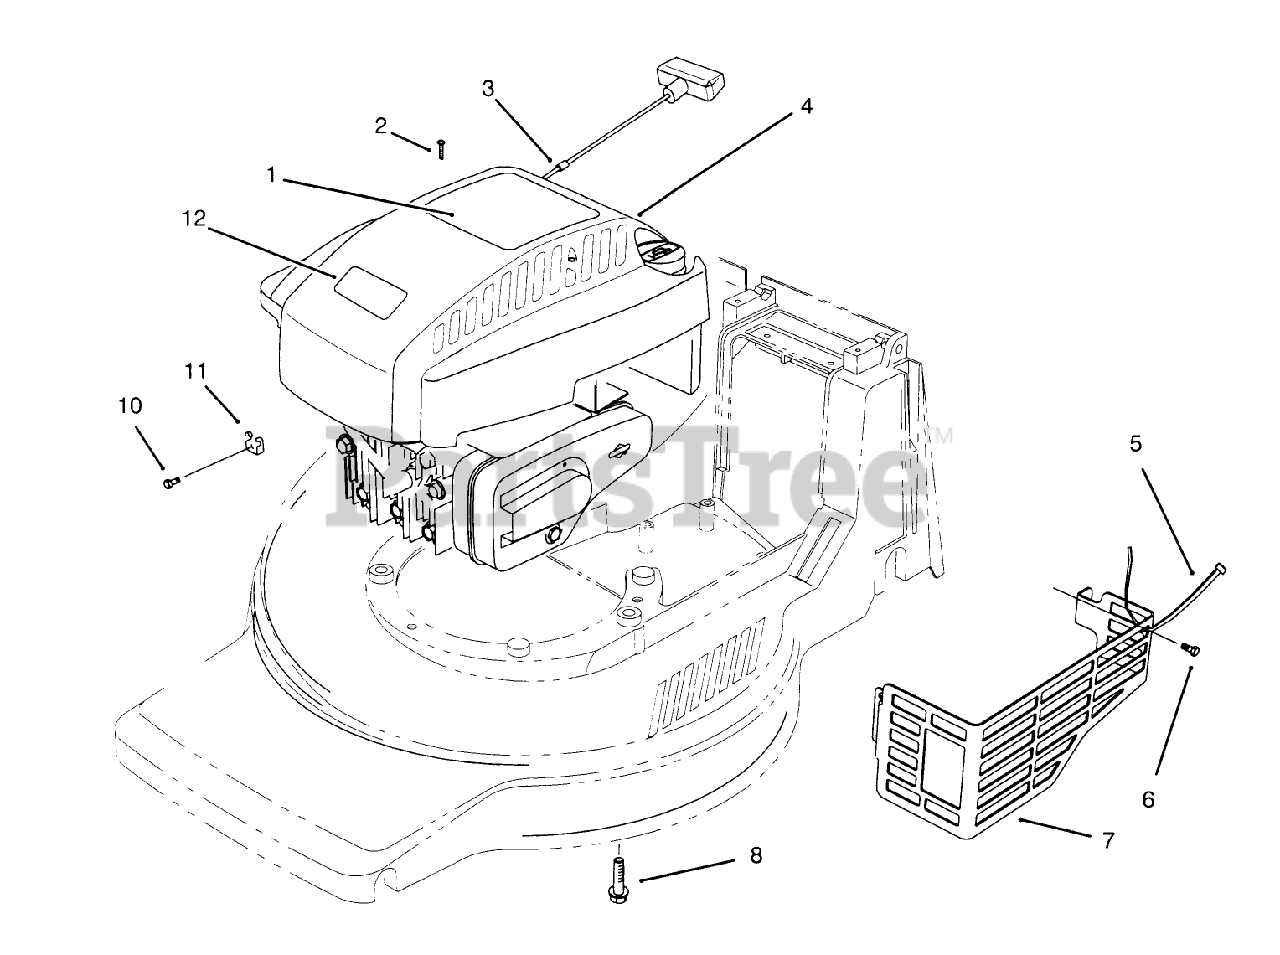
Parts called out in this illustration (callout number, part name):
1	DECAL - SHROUD
2	SCREW-PPH
3	STOP-ROPE
4	SHROUD-ENGINE
5	TIE-CABLE
6	SCREW-HWH
7	SHIELD-MUFFLER
8	SCREW-HWH
10	SCREW-CLAMP
11	CLAMP-CASING
12	PLATE-LOGO
